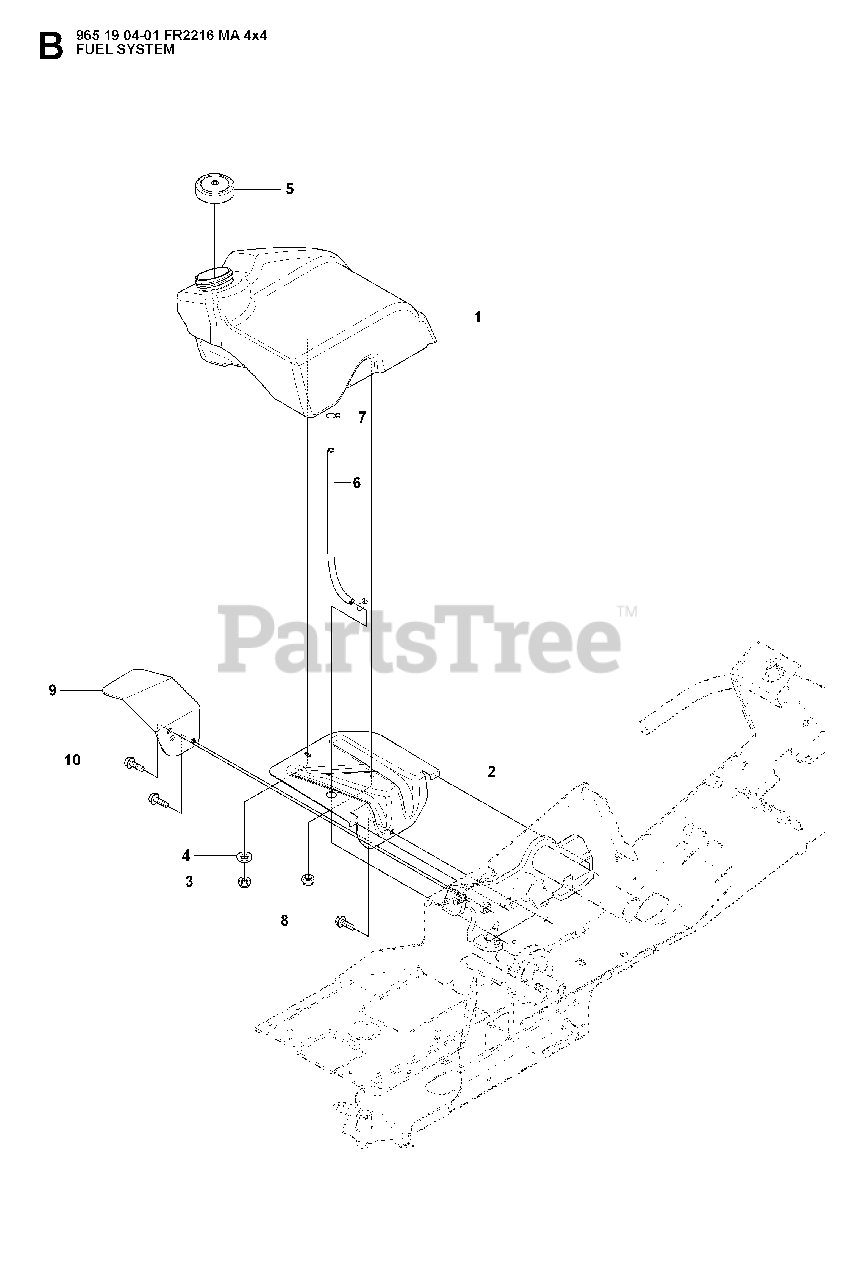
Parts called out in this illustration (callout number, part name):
3	LOCKNUT M6
4	WASHER
10	SCREW M10X25
